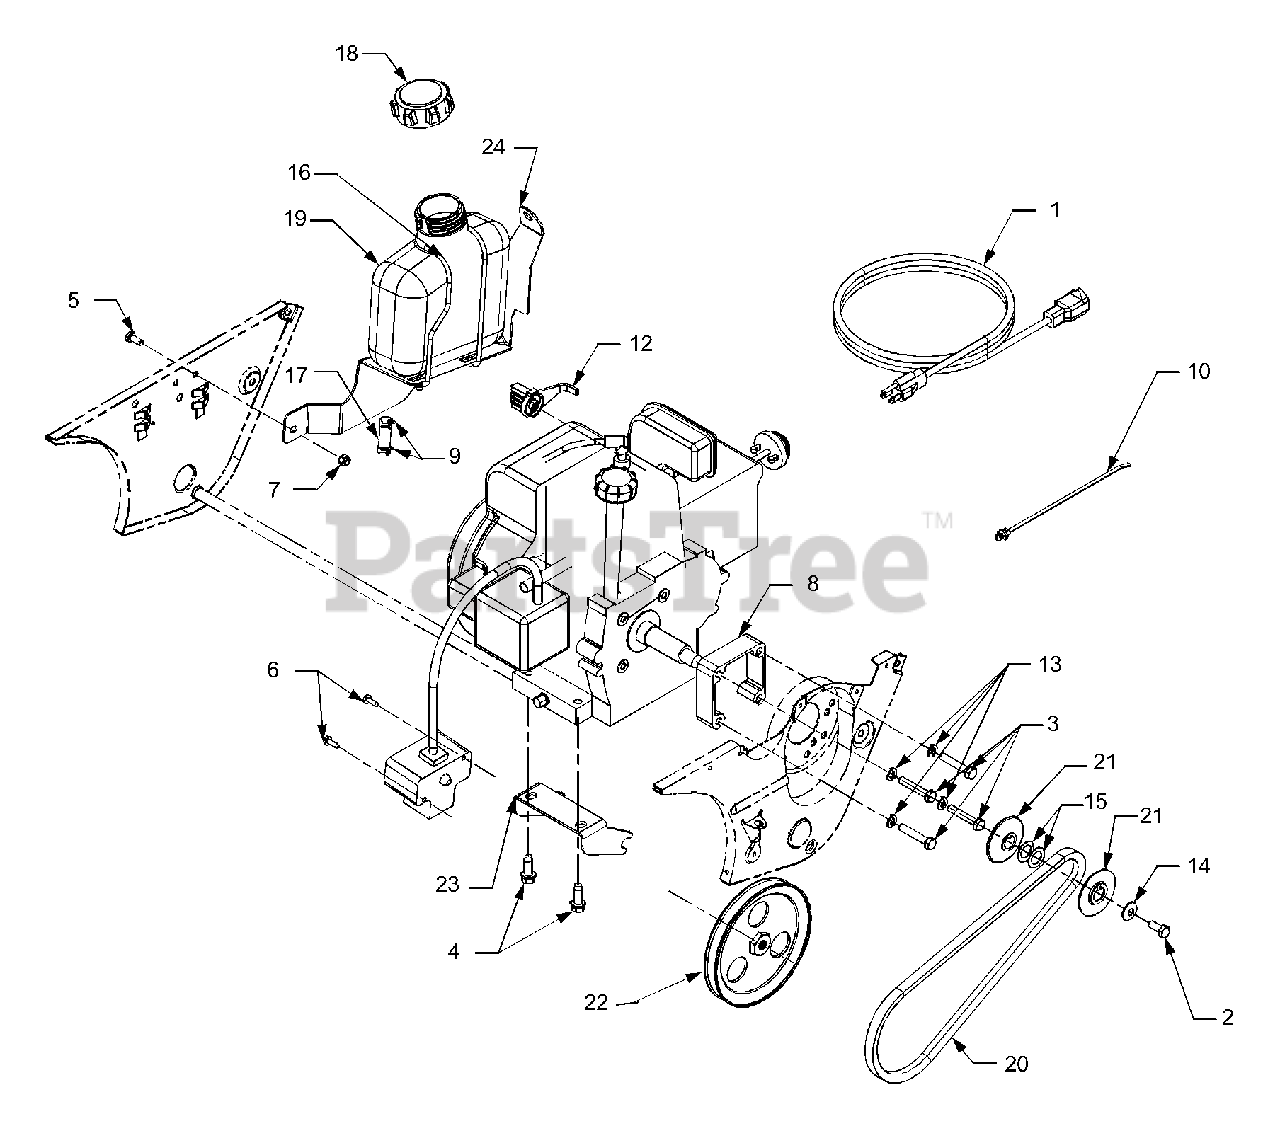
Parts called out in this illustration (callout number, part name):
1	Extension Cord
2	Hex Screw, 5/16-24 x .75
3	Hex Screw, 5/16-24 x 1.75
4	Self Tapping Screw, 3/8-16 x 1.00
5	Hex Screw, 1/4-20 x .62
6	Screw, #10-16 x .625
7	Hex Nut, 1/4-20 Nylon
8	Spacer, Engine 4 Cycle
9	Clamp, Hose
10	Cable Tie
12	Knob, Choke
13	Washer, Lock 5/16
14	Bell Washer, .340 x .872 x .060
15	Flat Washer, 5/8 ID x 1.0 OD
16	Support, Wire Gas Tank
17	Hose, Fuel Line
18	Cap, Fuel
19	Tank, Fuel
20	V-Belt 1/2 x 35.0 LG
21	Pulley Half, .625 ID x 2.25 OD
22	Pulley, 1/2 V 1/2-20 LH x 6.0
